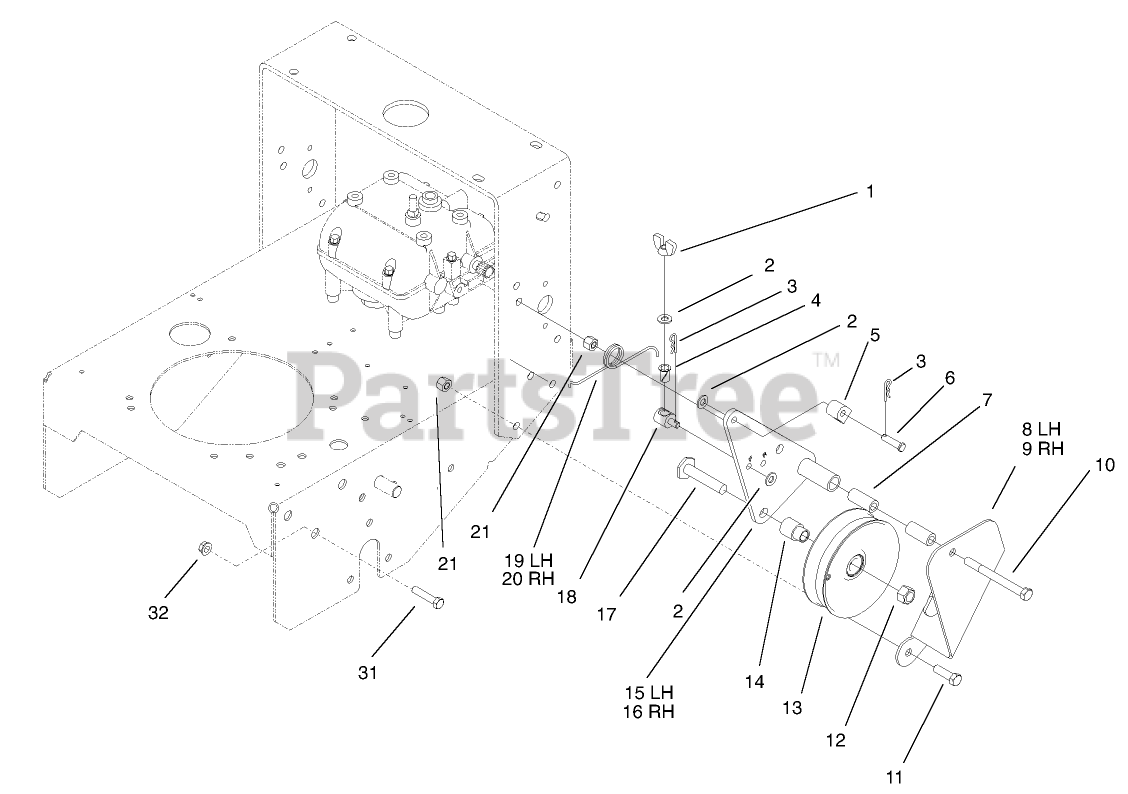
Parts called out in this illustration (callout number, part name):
1	NUT-WING
2	WASHER-PLAIN
3	PIN-COTTER
4	BUSHING-NYLON
5	FITTING-ROD
6	PIN-CLEVIS
7	SPACER-PIVOT, IDLER
8	BRACKET-SUPPORT, LH
9	BRACKET-SUPPORT, RH
10	SCREW-HH
11	SCREW-HH
12	NUT-LOCK, NI
13	PULLEY-IDLER
14	SPACER-PULLEY
15	BRACKET-IDLER, LH
16	BRACKET-IDLER, RH
17	SCREW-LEVELER
18	FITTING-ROD
19	SPRING-TORSION, LH
20	SPRING-TORSION, RH
21	NUT-LOCK, NI
31	SCREW-HHF
32	NUT-HF
